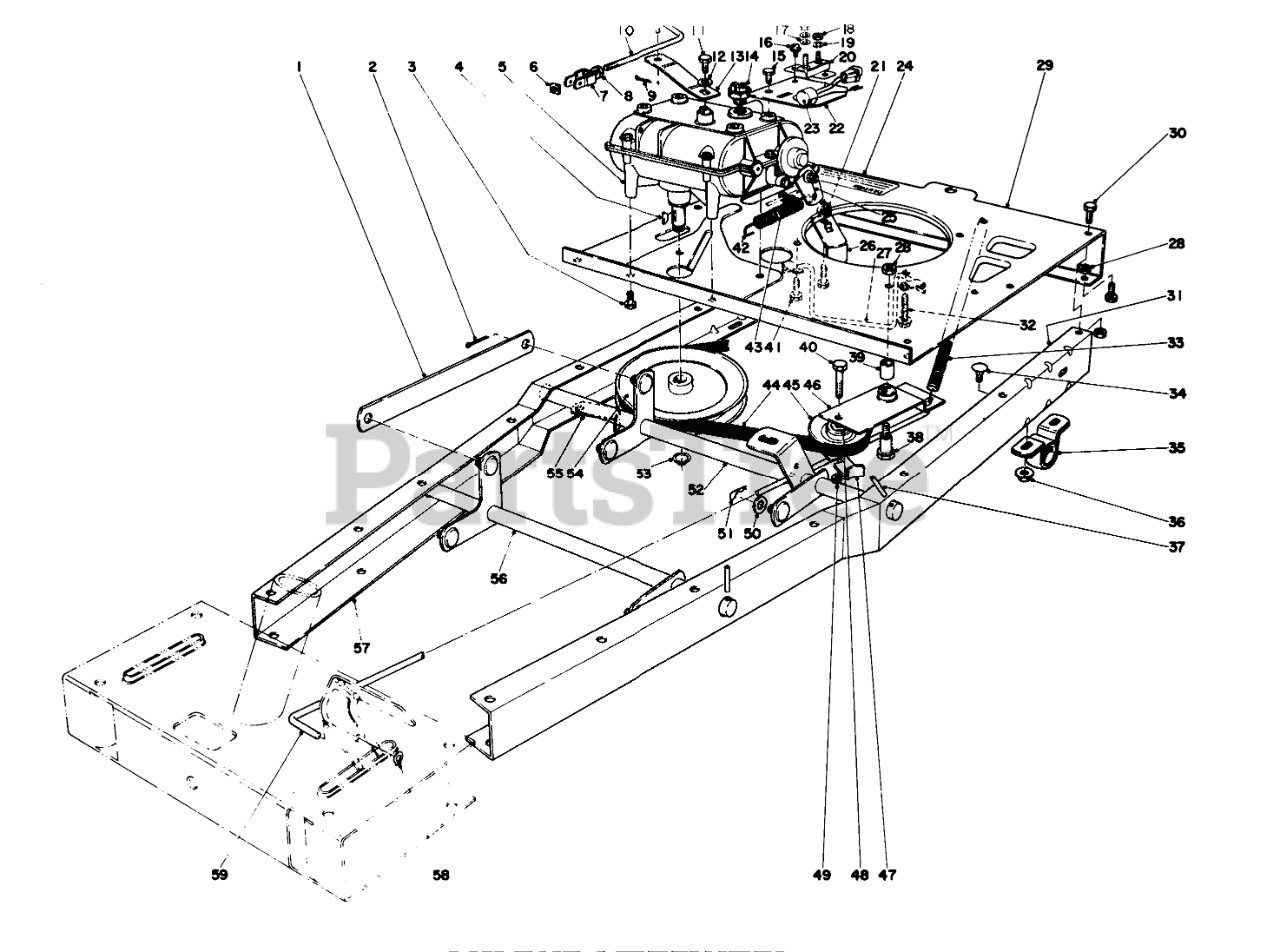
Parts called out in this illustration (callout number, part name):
1	Linkage-Height Adj.
2	PIN-COTTER
3	5/16-18 X 5/8 SEMS SC
4	KEY-WOODRUFF
5	Transmission
6	Nut-Square
7	Bracket-Rod Support
8	NUT-HEX, SIDE DEFORM
9	PIN-COTTER
11	SCREW-HH
12	WASHER-LOCK
13	Linkage-Transmission
14	SWITCH
15	SCREW-HHF
16	10-16 X 3/8 THDG SCREW
17	WASHER-FLAT
18	NUT-HEX
19	WASHER-LOCK/SP
20	Breaker, Circuit (Model 56025 only)
21	WASHER-PLAIN
22	Bracket-Charge Plug
23	Control Module
24	Decal
25	Spring-Brake Return
26	Belt Retainer
27	Belt Guide
28	NUT-LOCK, CONE
29	Engine Mounting Plate
30	SCREW-HH
31	Frame Chanel, L.H.
32	SCREW-HWHTF
33	Clutch Tension Spring
34	SCREW-CARR
35	PILLOW BLOCK
36	NUT-HF
37	PIN-ROLL, SLOTTED
38	CLUTCH PIVOT BOLT
39	BUSHING
40	SCREW-HH
41	Sems Screw
42	Spring Brake
43	Cable Holder
44	V-BELT
45	PULLEY-IDLER
46	Traction Idler (Incl. Ref. No. 39)
47	RETAINER-BELT
48	Washer
49	NUT-LOCK, CONE
50	WASHER-FLAT
51	PIN-COTTER
52	Height Adjustment
53	RING-SNAP, EXTERNAL
54	PULLEY
55	TRANS BELT RET B
56	FRONT LIFT WA B
57	Frame Channel R.H.
58	Retaining Ring
59	CLUTCH ROD
